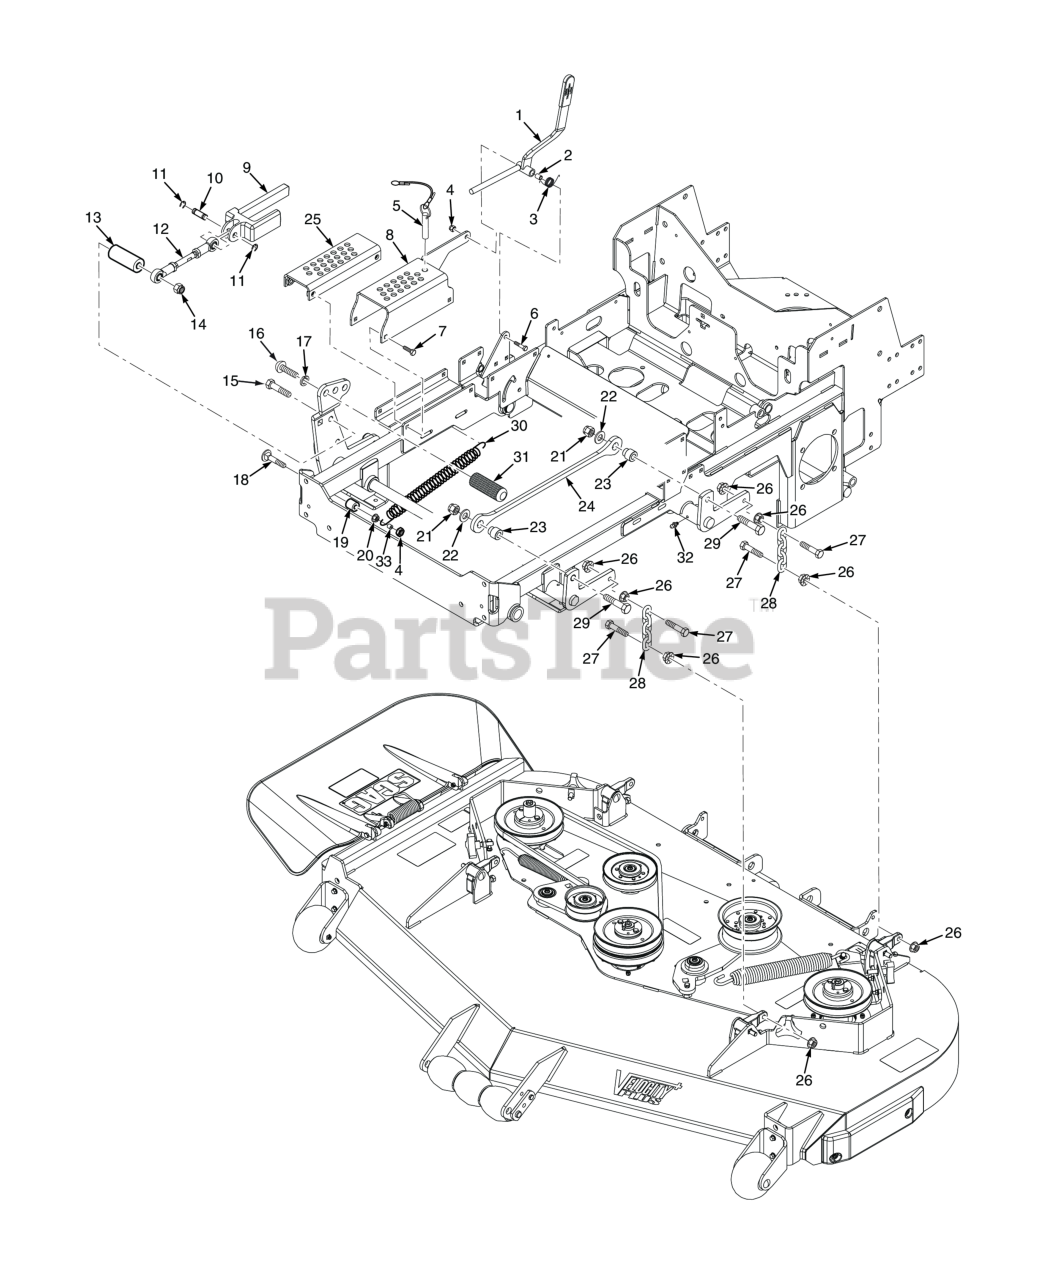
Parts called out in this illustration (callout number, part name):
1	Deck Latch Assembly (Includes Grip)
2	Spacer, Deck Latch
3	Spring, Torsion - Lever Return
4	Bolt, Hex Head 3/8-16 x 1" Ser. Flg.
5	Lanyard, Deck Height Pin Assembly
6	Capscrew, Hex Head 3/8-16 x 2-1/2"
7	Bolt, Hex Wshr Head 5/16-18 x 1-1/4"
8	Adjustment Bracket, Cutting Height
9	Slide, Height Adjust (INCL. 10,11,12)
10	Pin, Deck Lift
11	Retaining Ring, 1/2" Ext. "E"
12	Linkage Assembly, Deck Lift
13	Spacer, Deck Lift Pedal
14	HEX LOCKNUT, ELASTIC STOP, 1/2-13
15	Bolt, Hex Head 1/2-13 x 4" (lower)
16	Capscrew, 5/8-11 x 1-1/2"
17	Lockwasher, 5/8" Spring
18	Carriage Bolt, 3/8-16 x 2-1/2"
19	Yoke, Front Caster Wheel
20	NUT, 3/8-16 SERRATED FLANGE HEX HEAD
21	HEX LOCKNUT, ELASTIC STOP, 1/2-13
22	Flat Washer, 1/2 (.562 x 1.375 x .109)
23	Pivot, Deck Link
24	Link, Decklift (black)
25	Adjustment Bracket, Lower Cut Height
26	NUT, 3/8-16 SERRATED FLANGE HEX HEAD
27	Bolt, Hex Head 3/8-16 x 1-1/2" B&S 32BV
28	Chain, Deck Lift
29	Bolt, Hex Head 1/2-13 x 2-1/4"
30	Spring, Decklift
31	Foot Pedal, Height Adjustment
32	GREASE FITTING, STR. 1/4-28 SELF TAP.
33	Spacer, Deck Assist
